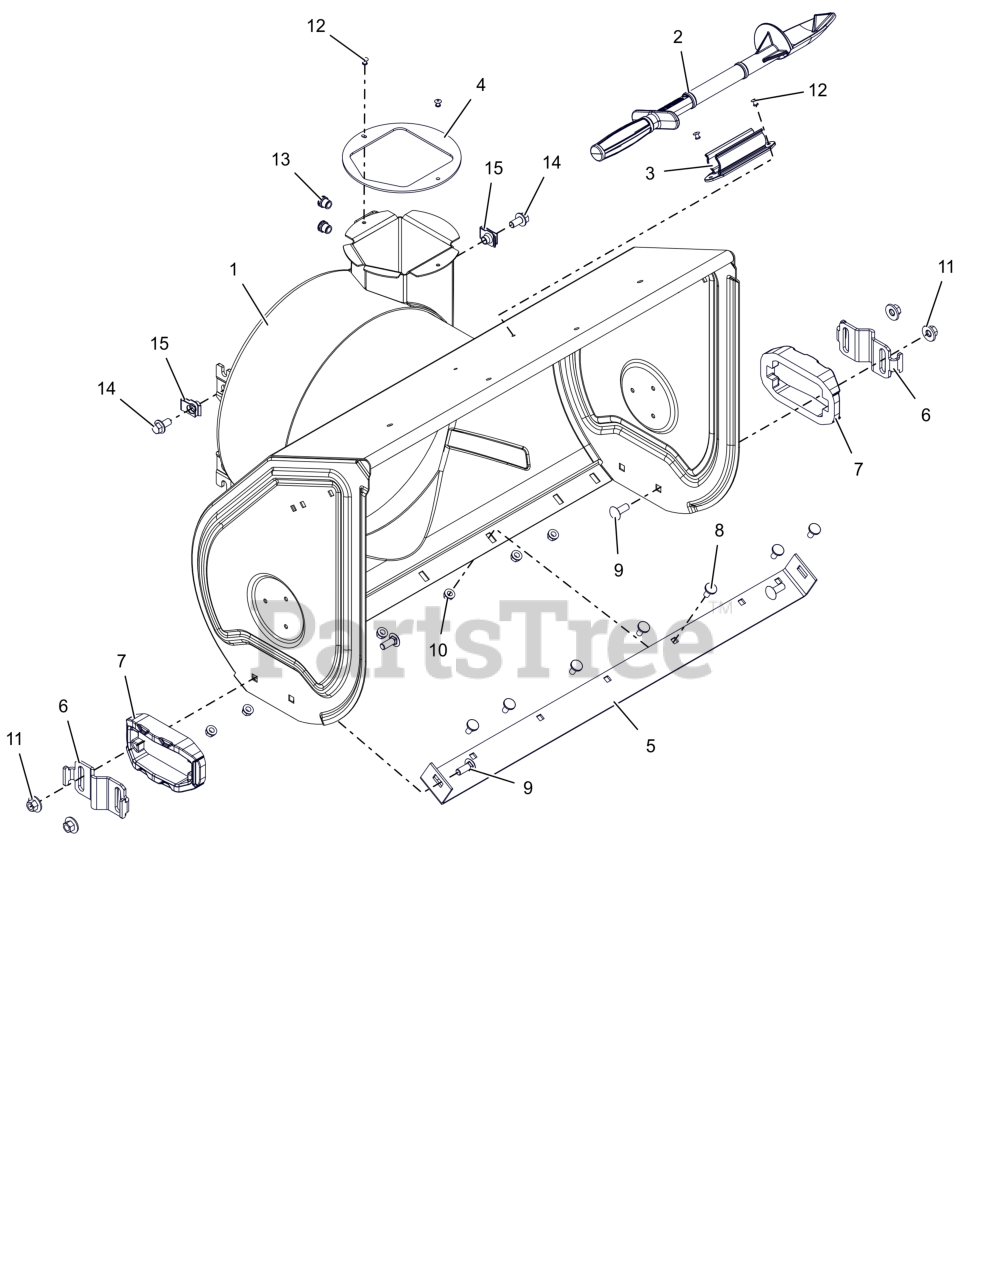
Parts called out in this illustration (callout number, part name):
1	HOUSING, BLOWER W/SAFETY DECAL 30"
2	DEVICE, SNOW CLEAN OUT
3	MOUNT, SNOW CLEAN OUT
4	BAFFLE, DISCHARGE NECK
5	BLADE, SCRAPER-30"
6	SHOE, SKID - INSERT (BLACK)
7	SHOE, SKID - WEAR
8	BOLT, MODIFIED HEAD CARRIAGE
9	BLT,RHSSN .38-16X1.00 G5 ZCC
10	NUT-LK-TOP-FLG .312-18 GF ZCC
11	NUT- CON-LN .375-16 ZC120
12	RVT, POP .1875 ZCC
13	NUT,THD,INSERT .38-16 ZC120
15	NUT-RTNR .375-16X.37
